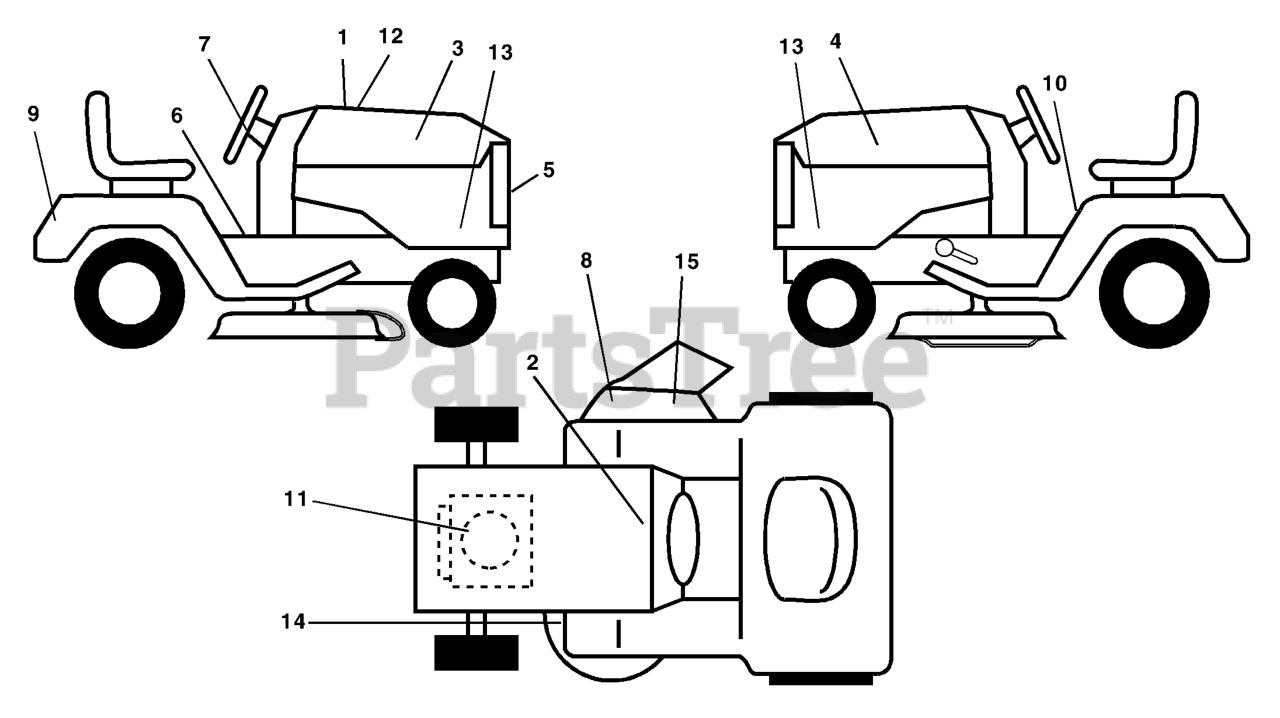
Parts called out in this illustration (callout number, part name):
1	DECAL HOOD CUST. RESP.
2	DECAL BTRY SYMBOLS
3	DECAL HOOD RH
4	DECAL HOOD LH
5	DECAL.GRILLE.HUSQ
7	DECAL.WHEEL.STEERING.HUSQ.PERM
8	DECAL.WARN.KEEP.HAND.AWAY
9	DECAL, FENDER
10	DECAL FENDER DANGER
11	DECAL ENGINE
12	DECAL HOOD
13	DECAL HOOD SIDES
14	DECAL V BELT SCHEMATIC
15	DECAL DECK "B" 42"
